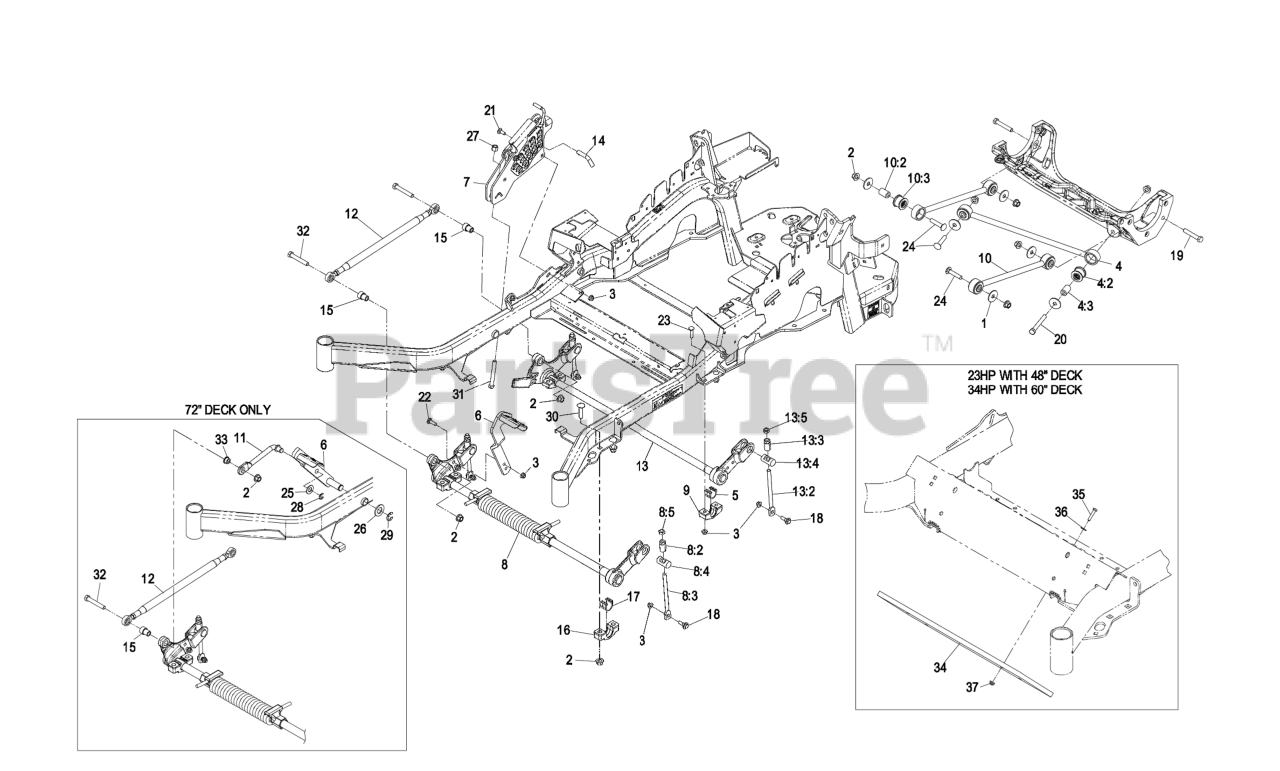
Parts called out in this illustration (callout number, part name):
1	WASHER-THRUST
2	Nut-Lock 1/2-13
3	NUT-HF, NI
4	PANHARD ROD ASM
4:2	BUSHING-SUSPENSION, RUBBER
5	BEARING-CROSS SHAFT, REAR
6	LEVER-FOOT
7	HOC ASM
8	FRONT DECK LIFT ASM
8:2	ADJUSTER-LIFT, DECK
8:3	LINK-ADJUSTER, DECK LIFT
8:4	TRUNNION
8:5	NUT-JAM
10	DECK STRUT ASM
10:2	BUSHING-SUSPENSION, RUBBER
11	LINK-LEVER, FOOT
12	SIDE LINK ASM
13:2	LINK-ADJUSTER, DECK LIFT
13:3	ADJUSTER-LIFT, DECK
13:4	TRUNNION
13:5	NUT-JAM
14	PIN-HOC
15	BUSHING-FLANGE
16	SUPPORT-CROSS SHAFT, BEARING
17	BEARING-CROSS SHAFT, FRON
18	SCREW-SHOULDER, HHF
19	SCREW-HH
20	SCREW-HH
21	BOLT-CARR
22	Bolt-Carriage 3/8-16 X 1 1/4
23	SCREW-CARR
24	SCREW-CARR
25	WASHER-FLAT
26	WASHER-FLAT
27	NUT-LOCK, NI
29	RING-RETAINING, EXT
30	SCREW-CARR, SHORT NECK
31	BOLT-TAP
32	SCREW-HH
33	BUSHING-FLANGE
34	WEIGHT,TOE BOARD
35	SCREW-HH
36	WASHER-FLAT
